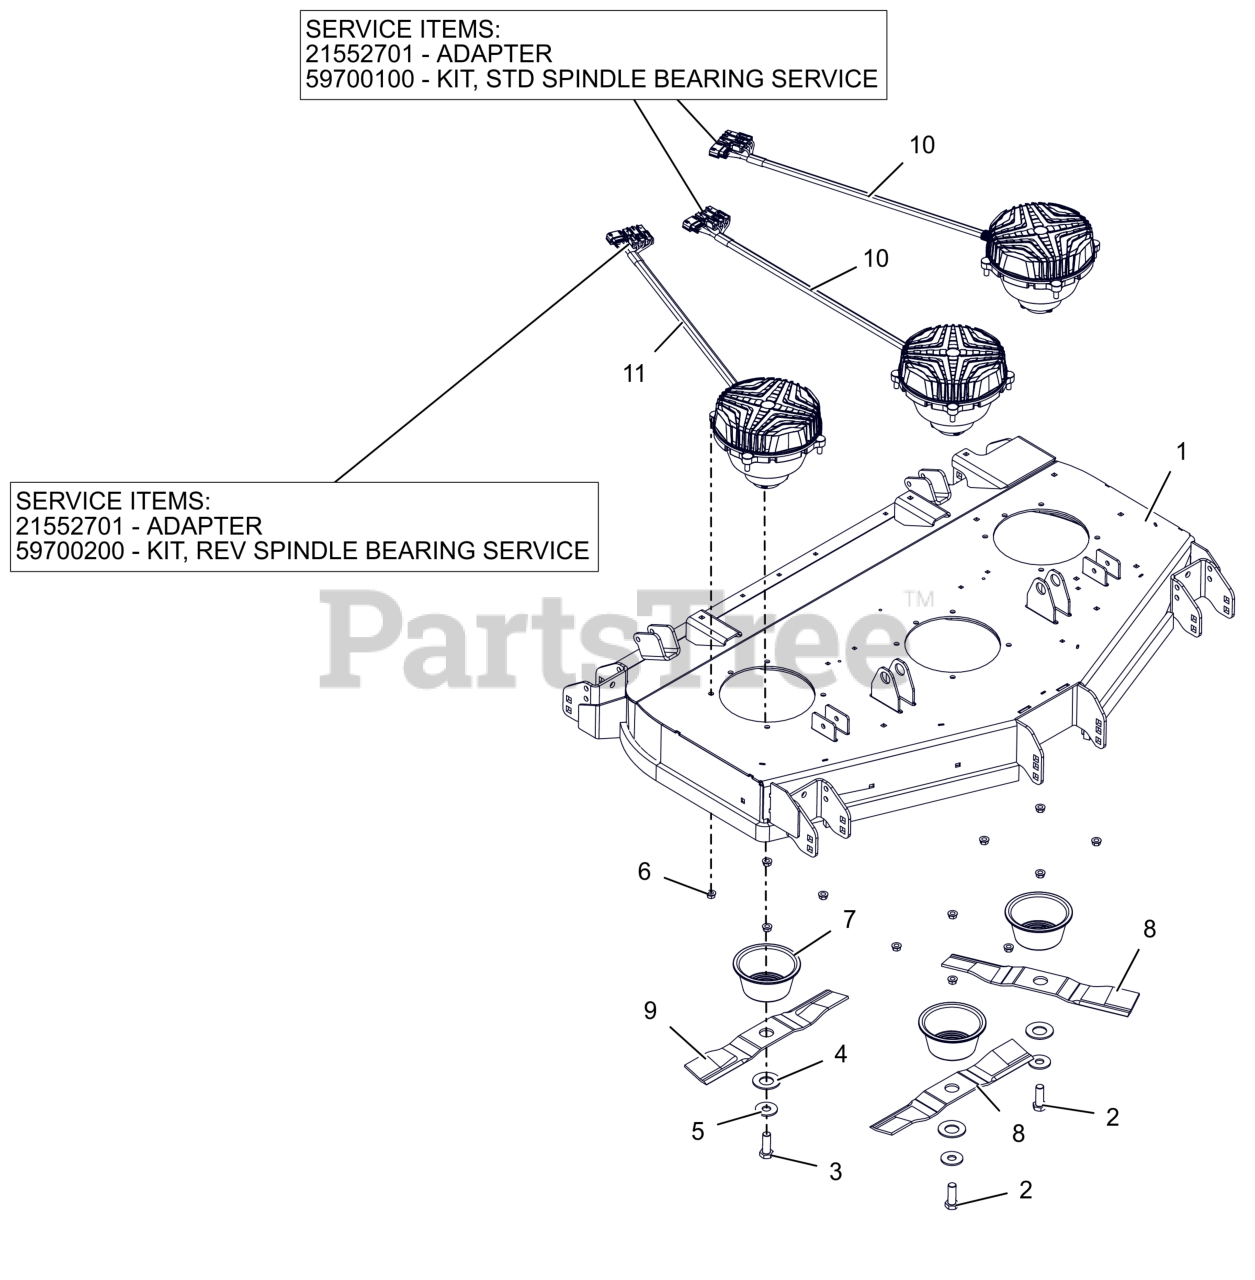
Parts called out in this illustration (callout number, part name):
1	WLDMT, 48" PSEV REAR DISCHARGE DECK (ORANGE)
2	BLT, HEX .62-18X1.75 G8 ZCC
3	BLT, HEX 0.625-11X1.75 GR8 ZCC LH
4	WSHR, BLVL - .56X28.5X3 PHOS.COAT
5	WSHR, HRDN 0.687X1.75X0.134 HRD
6	NUT-LK-CTR-FLG .375-16 GF ZCC
7	GUARD, SPINDLE LOWER
8	BLADE- MOWER-16.19" LOW
9	BLADE, MOWER -16.190" EFF CCW
10	MOTOR, DECK - 48"/52" CW
10	ADAPTER
10	KIT,STD SPINDLE BEARING SERVICE
11	MOTOR, DECK - 48"/52" CCW
11	ADAPTER
11	KIT,REV SPINDLE BEARING SERVICE
